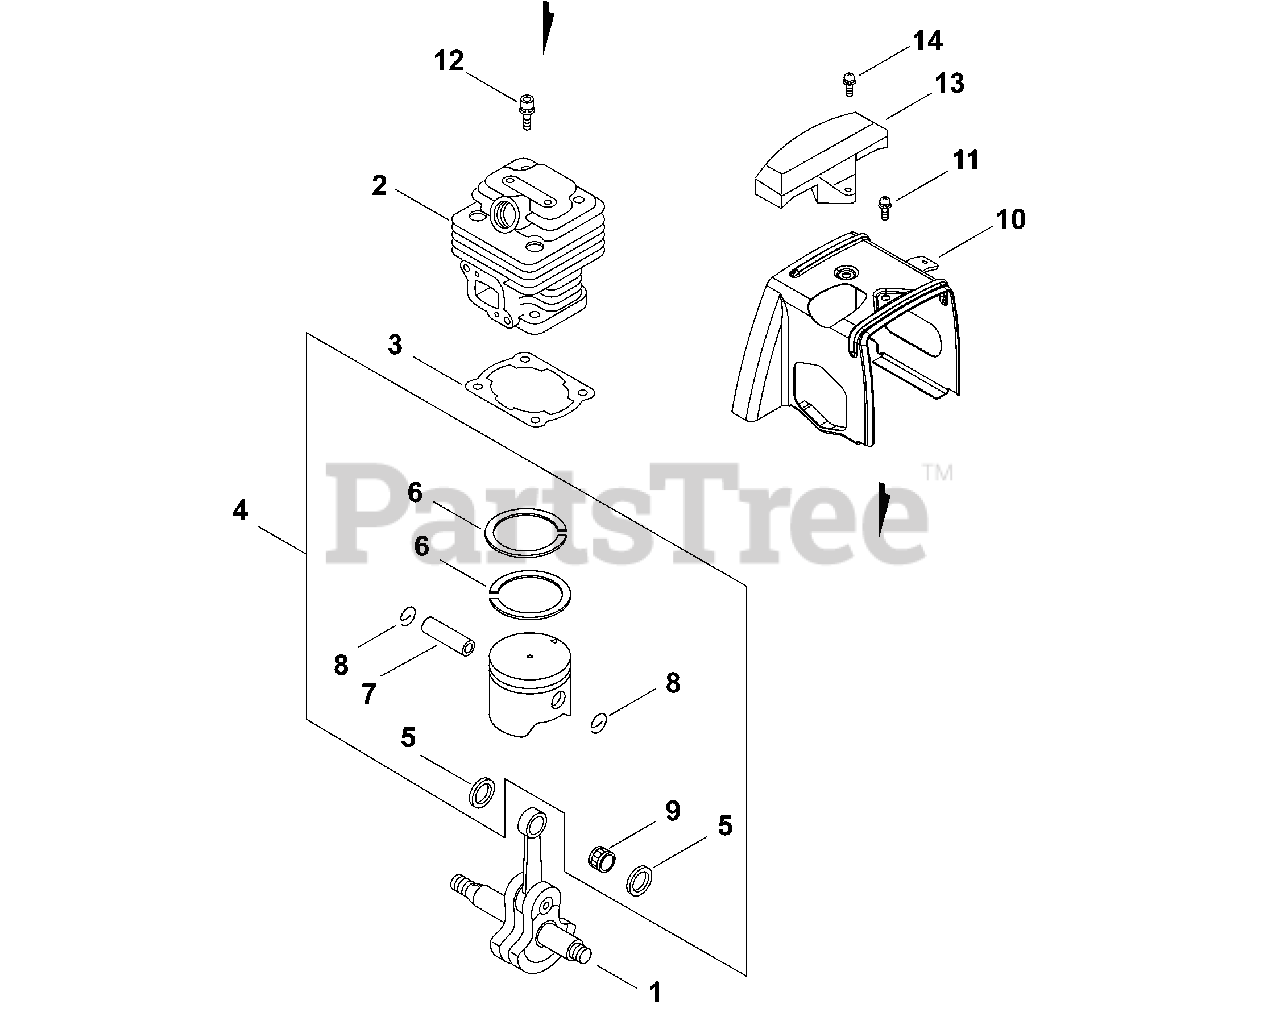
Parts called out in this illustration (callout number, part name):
1	CRANKSHAFT ASSY
2	CYLINDER
3	GASKET, CYLINDER
4	PISTON KIT
5	WASHER, THRUST 10
6	RING, PISTON
7	PIN, PISTON
8	RING, SNAP Ø10
9	BEARING, NEEDLE 10
10	COVER, CYLINDER
11	SCREW 5×10
12	BOLT 5×20
13	GUARD, TOP
14	SCREW 5×14
